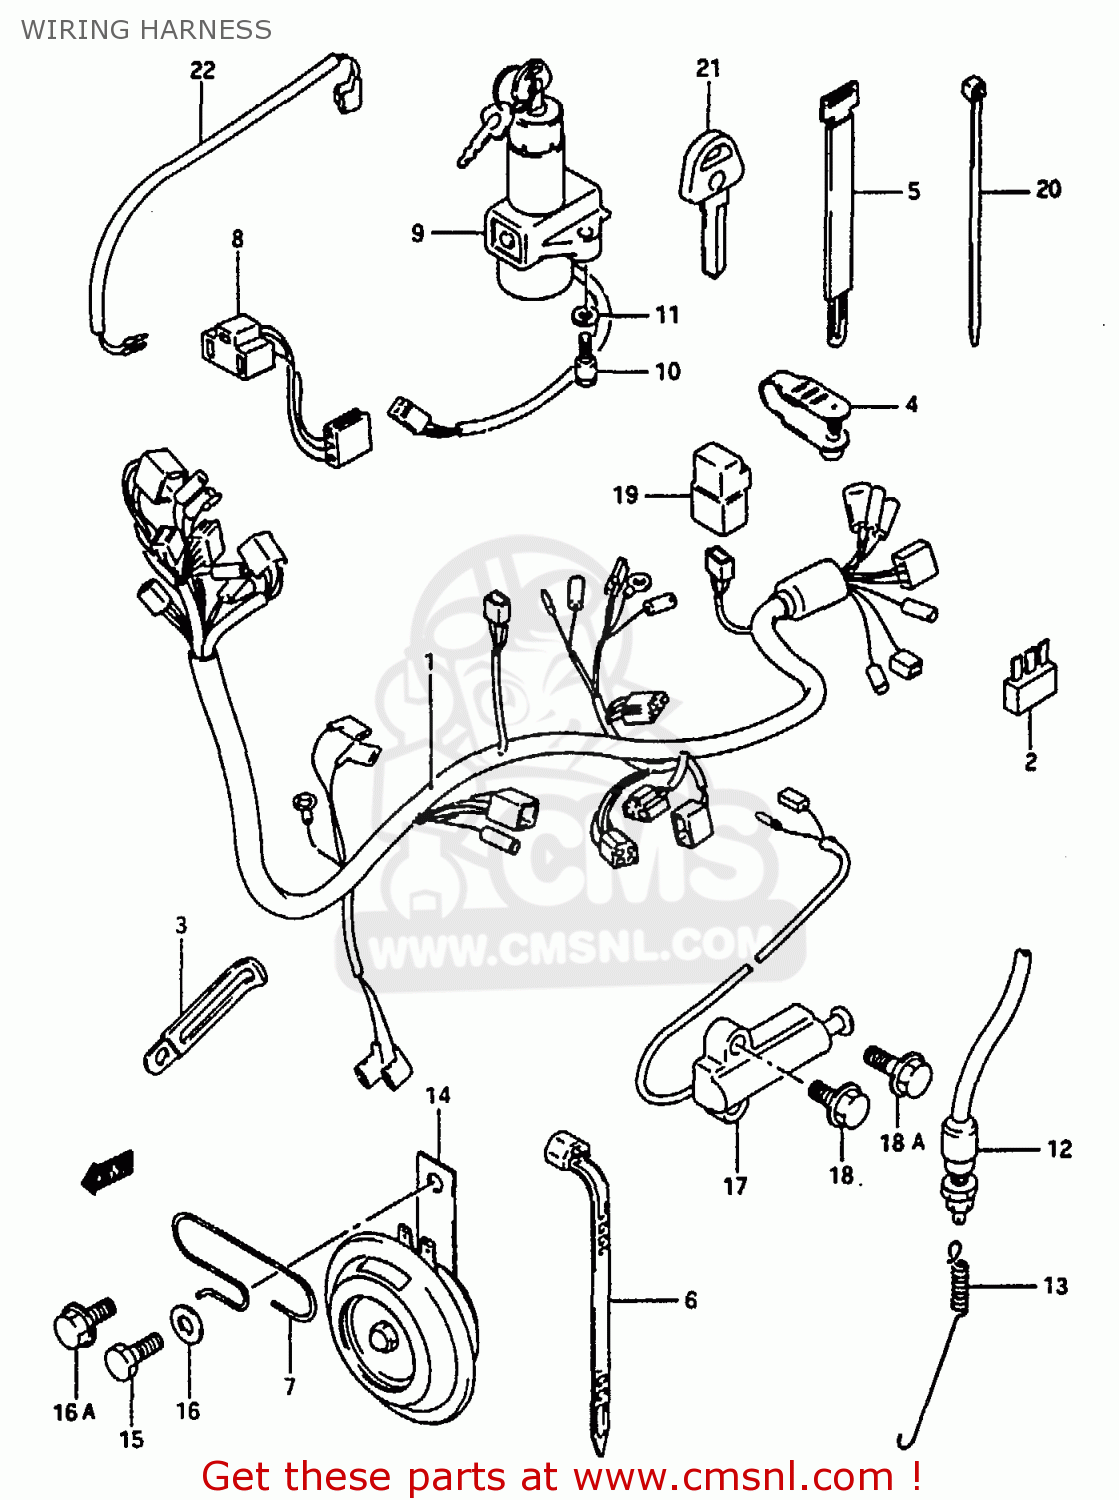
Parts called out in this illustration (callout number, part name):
1	HARNESS,WIRING
2	DIODE(STANLEY DE8804)
3	CLAMP
4	CLAMP,L:88
5	CLAMP
6	CLAMP(L:125)
7	CLAMP,WIRING HARNESS
8	LEAD WIRE,HEADLAMP
9	SWITCH ASSY,IGNITION
10	BOLT
11	WASHER,LOCK
12	SWITCH ASSY,STOP LAMP
12A	SWITCH,REAR BRAKE LAMP
13	SPRING
14	HORN ASSY
15	BOLT
16	WASHER
16A	BOLT
17	SWITCH ASSEMBLY,SIDE STAND
18	BOLT
18A	BOLT
19	RELAY ASSY
20	CLAMP(L:145)
21	KEY,BLANK
22	WIRE,STOP LAMP SWITCH LEAD
